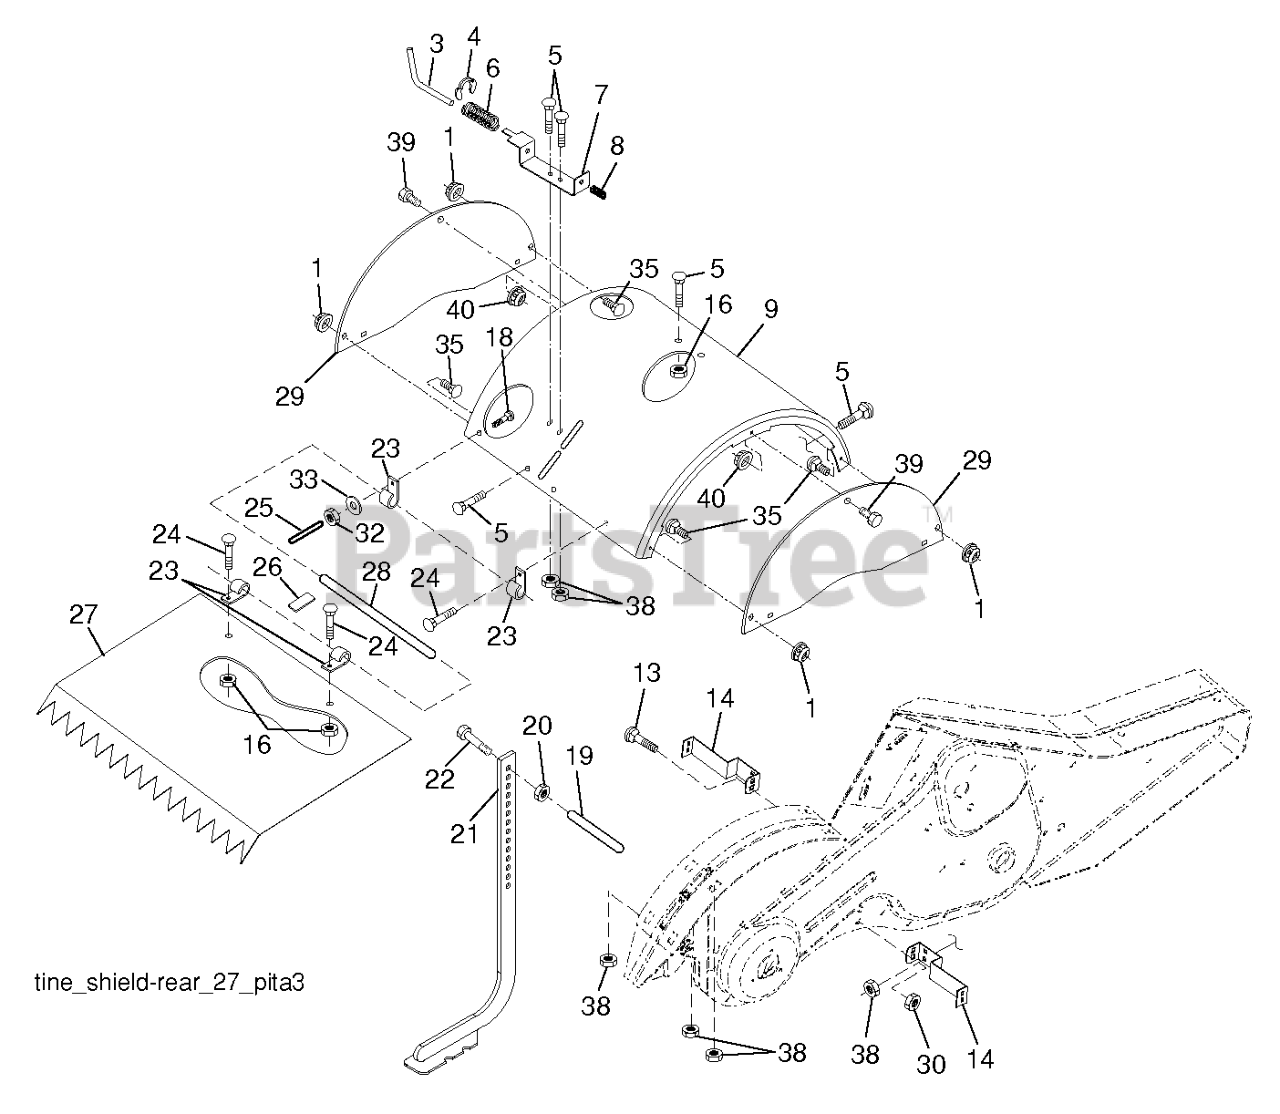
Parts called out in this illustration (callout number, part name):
1	NUT.FLANGE.5/16
3	STAKE PIN TI
4	RING, KLIP
5	BOLT, RDHD SQNK 5/16-18 X 3/4
7	BRACKET
8	SPRING CRT
9	SHIELD.TILLER.TINE.CRT14.ORNG
13	BOLT.CARRIAGE.5/16-18
14	BRACKET.TINE.SHIELD.BLACK
16	NUT T
20	NUT.HEX.3/8-16UNC
21	REPL BY 532 10 21-56
22	BOLT.375-16
24	BOLT
25	VINYL CAP TI
26	PAD IDLER TI
27	SHIELD.PNT.LEVEL.CRT.14.ORANGE
28	PIN.HINGE.TILLER
29	SHIELD.TINE.SIDE.ORANGE
30	LOCKNUT-FLANGE 5/16-18
32	NUT
33	LOCKWASHER
35	BOLT.CARR.5/16-18X5/8.SHORT
38	NUT
39	BOLT.HEX.HD.WASHER.5/16-18X.75
40	NUT.SPEED.5/16-18
